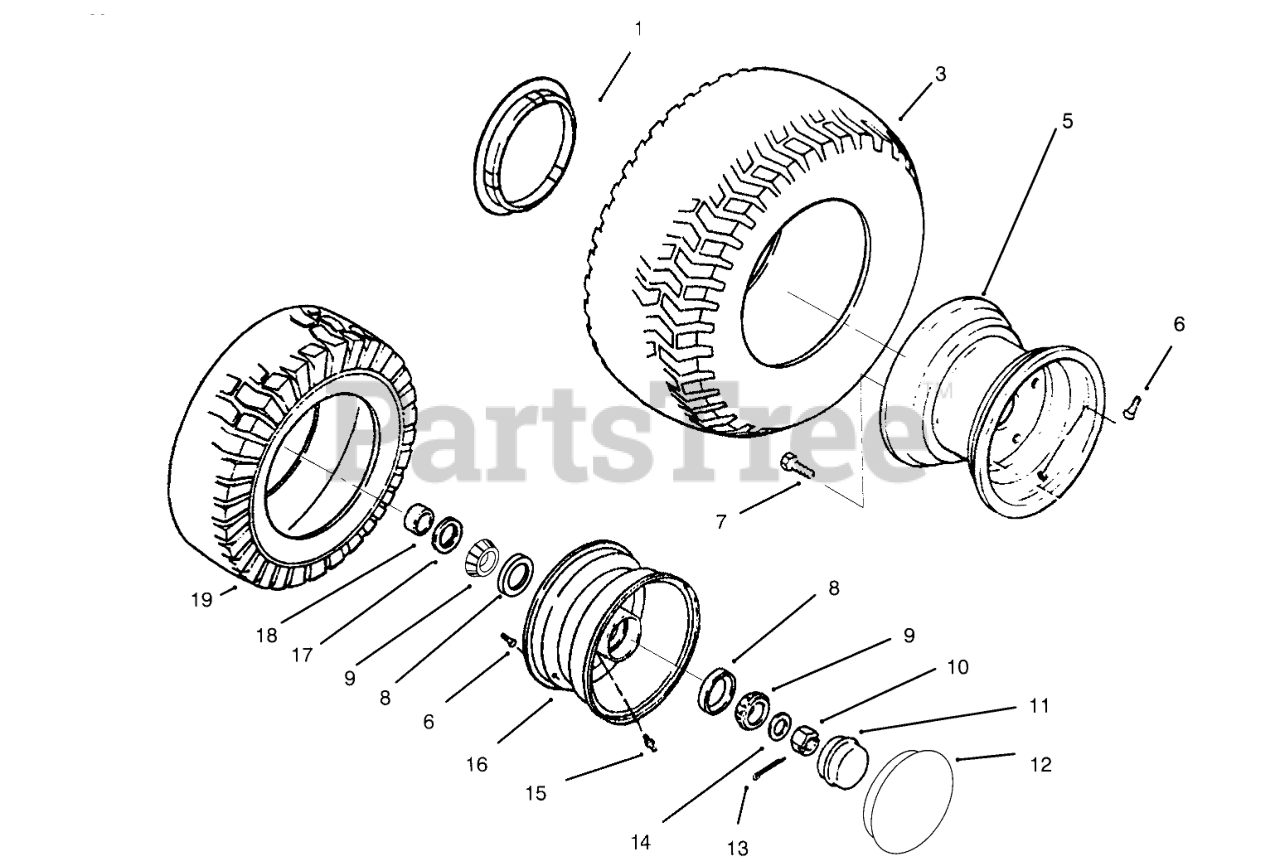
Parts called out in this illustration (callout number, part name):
1	12"-HUB CAP LOGO
3	TIRE 23 X 10.50-12
5	RIM ASM
6	VALVE
7	BOLT-LUG
8	Cup
9	Bearing
10	NUT-HEX, SLOTTED
11	DUST CAP
12	8"-HUB CAP LOGO
13	PIN-COTTER
14	WASHER
15	ZERK-GREASE
16	Wheel-Front (Includes Item 15 & Qty.2 of item 8)
17	Seal
18	SPACER
19	Tire-Turf Tray, Front 12 X 7.5-8
